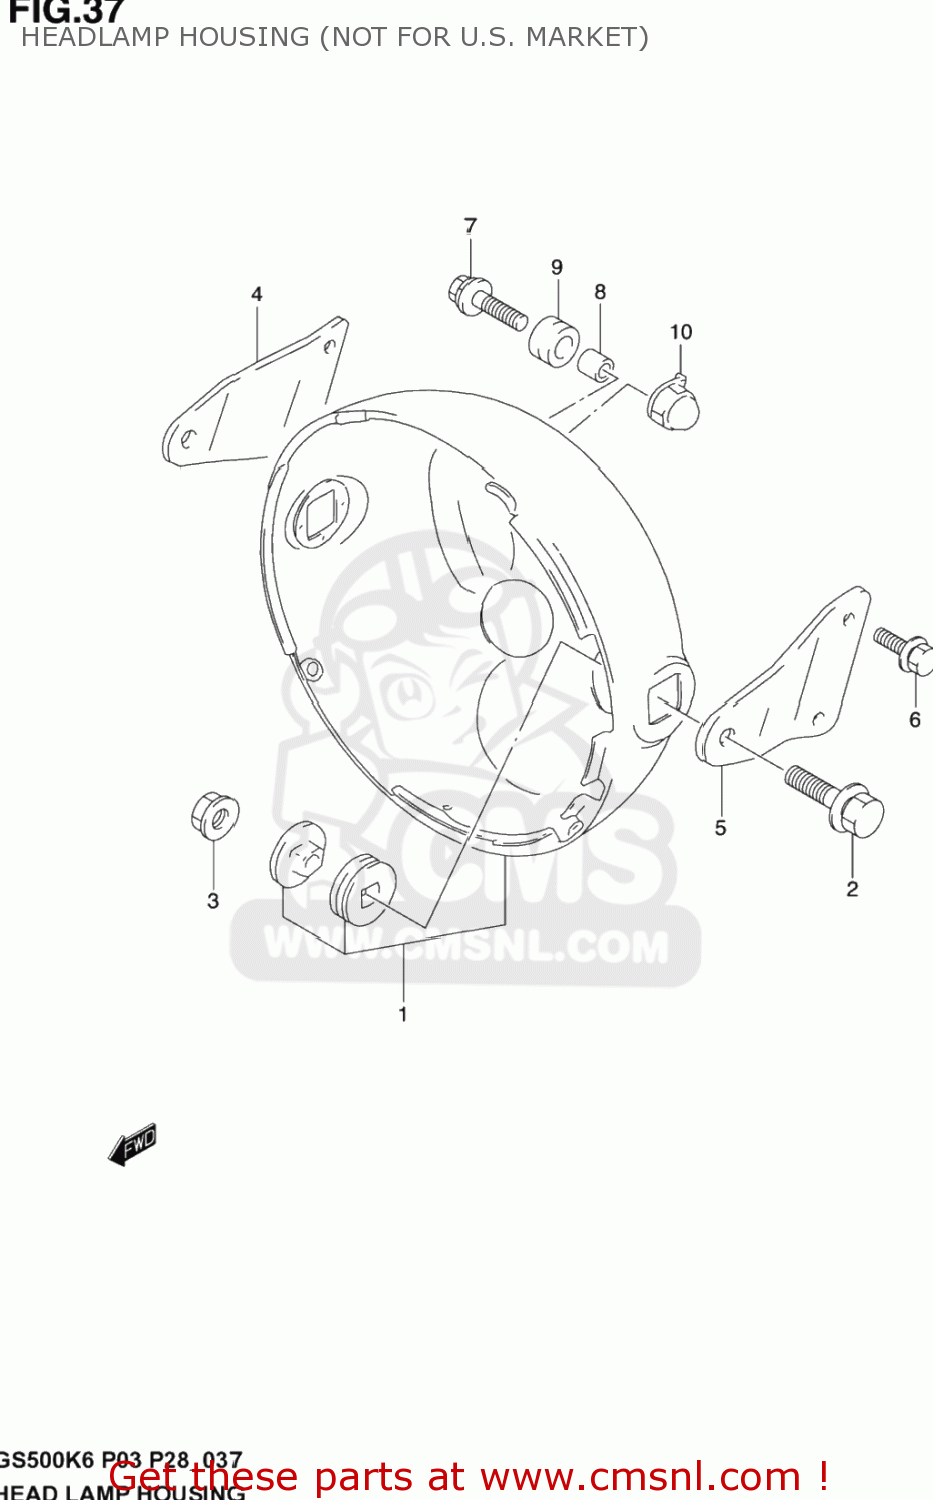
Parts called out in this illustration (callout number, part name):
1	HOUSING,HEADLAMP
2	BOLT
3	NUT
4	STAY,HEADLAMP
5	STAY,HEADLAMP
6	BOLT
7	BOLT
8	SPACER(6.5X10.5X12)
9	CUSHION
10	PLATE,HEADLAMP
